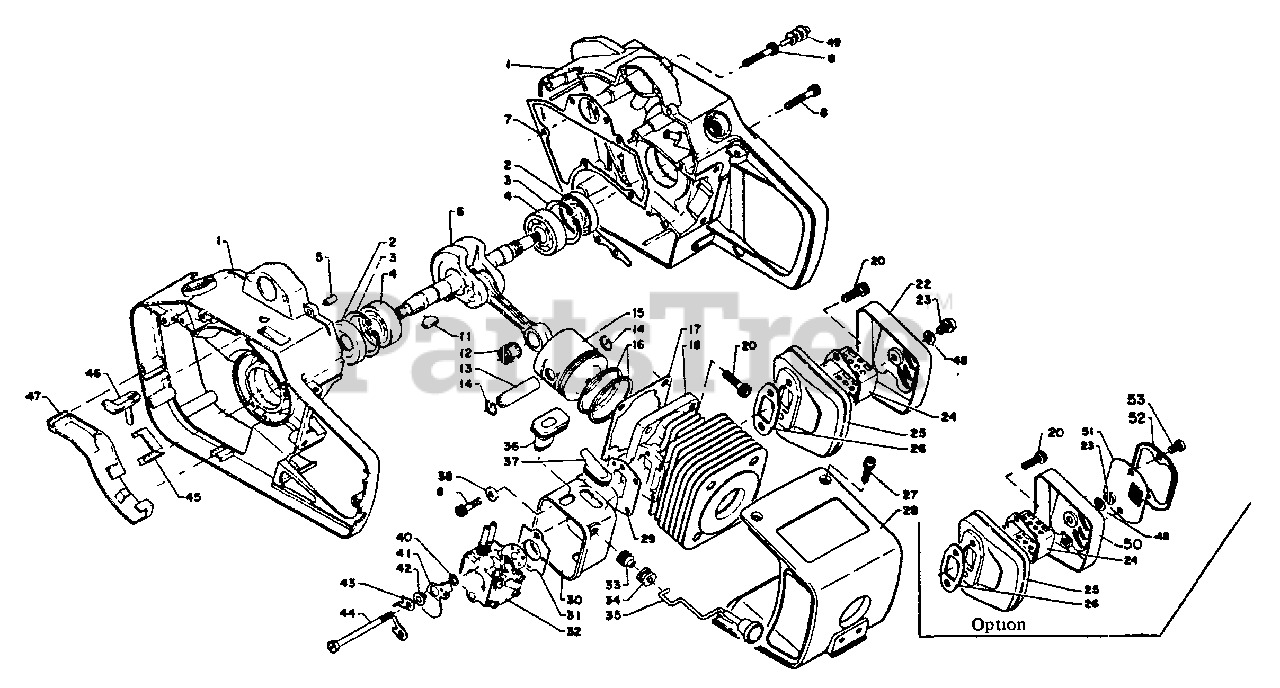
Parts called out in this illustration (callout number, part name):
1	CRANKCASE KIT
2	SEAL, OIL
3	RING, RETAINING - 32
4	BEARING, BALL - 6201
5	PIN - LOCATING
6	CRANKSHAFT ASSY
7	GASKET, CRANKCASE
8	SCREW - 4X25
12	BEARING, NEEDLE
13	PIN, PISTON
14	RING, RETAINING
15	PISTON
16	RING, PISTON
17	GASKET, CYLINDER
18	CYLINDER
20	SCREW - 5X20
22	LID, MUFFLER
23	SCREW - 5X8
24	BAFFLE, MUFFLER
25	MUFFLER
26	GASKET, EXHAUST
27	SCREW - 4X18
28	COVER, ENGINE
29	GASKET, INTAKE
30	INSULATOR, INTAKE
31	GASKET, INTAKE
32	CARBURETOR WA-25
33	GROMMET
35	ROD, CHOKE
36	GROMMET
37	GROMMET
38	WASHER
40	WASHER
41	SHUTTER, CHOKE
43	RETAINER
45	GUIDE, CABLE
46	CLAMP
47	CLAMP
48	LOCKWASHER - 5
49	SEAL, DUST
50	LID, MUFFLER
51	SCREEN, SPARK ARRESTOR
52	RETAINER, SCREEN
53	SCREW - 5X8
